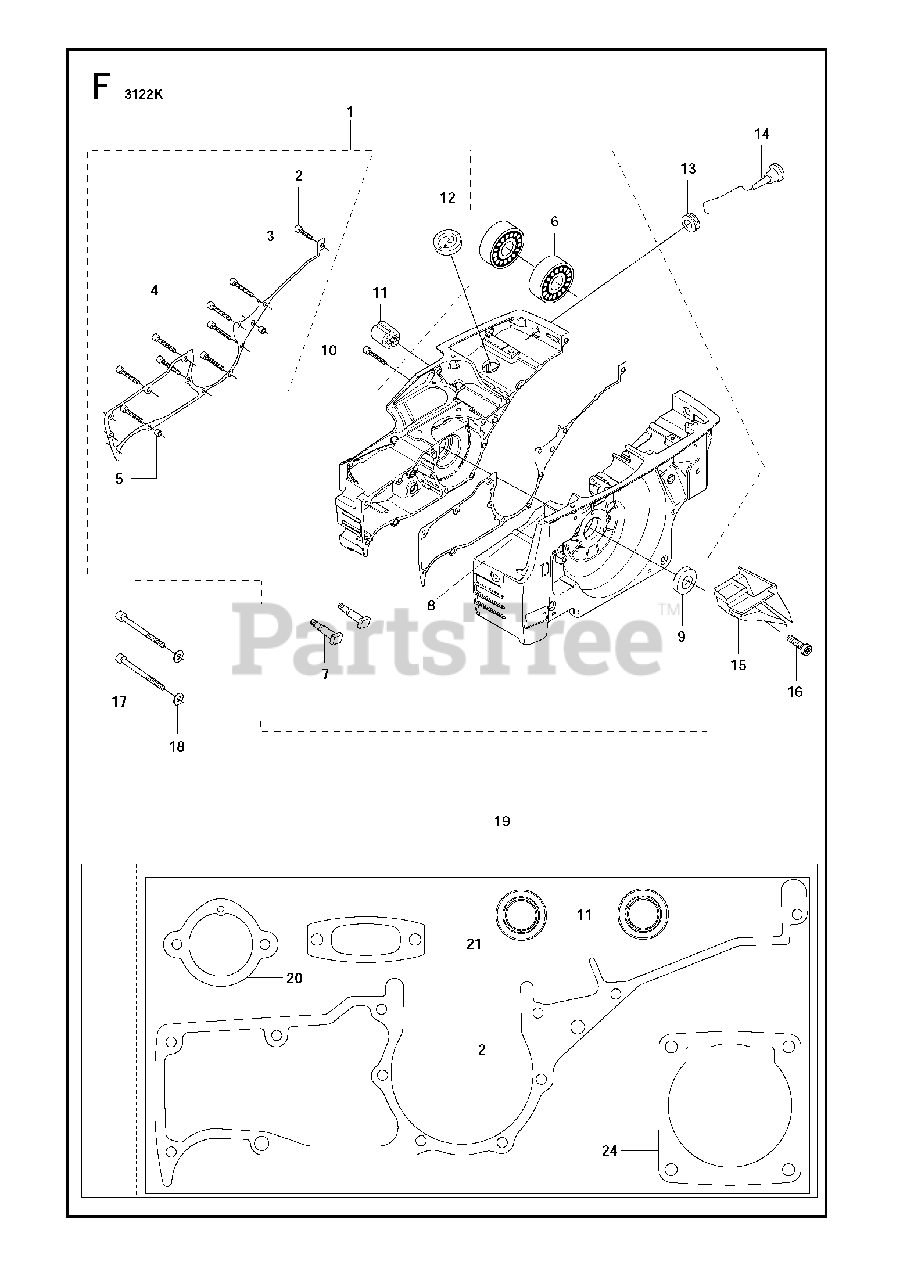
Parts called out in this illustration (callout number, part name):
2	SCREW ITXSCM
4	SCREW ITXSCM
5	GUIDE BUSHING
6	BALL BEARING
9	SEALING RING
10	SCREW ITXSCM
11	ANTIVIBRATION ELEMENT
14	CHOKE CONTROL
16	SCREW ITXSCM
17	SCREW ITXSCM
19	GASKET KITIncl. 3, 9, 10 - 22
